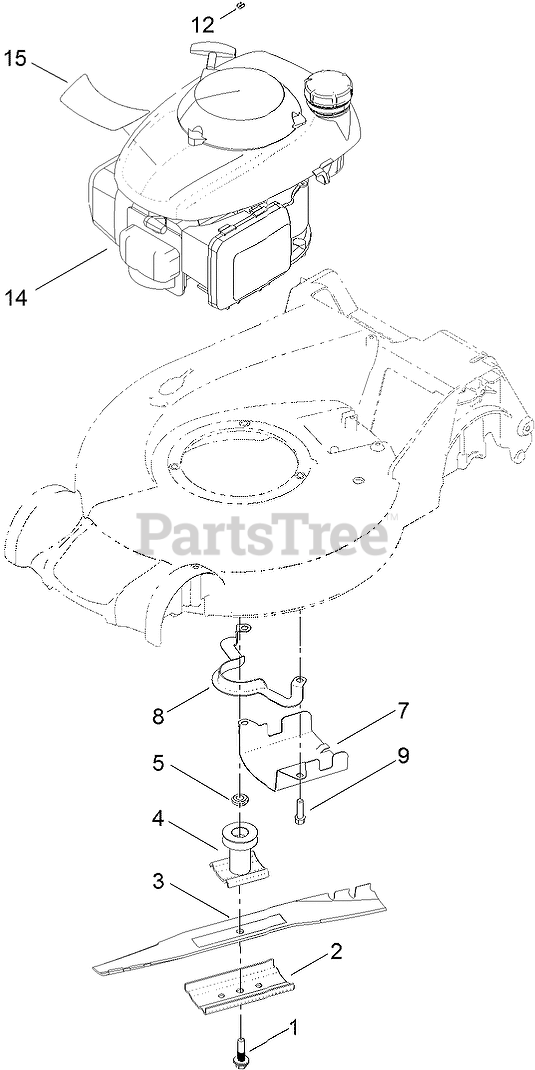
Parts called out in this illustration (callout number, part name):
1	BOLT-BLADE
2	SUPPORT-BLADE
4	DRIVER-BLADE
5	Spacer-Driver
7	SHIELD-GRASS
8	GUIDE-BELT
9	SCREW-MOUNT, ENGINE
12	STOP-ROPE
15	DECAL-ENGINE
